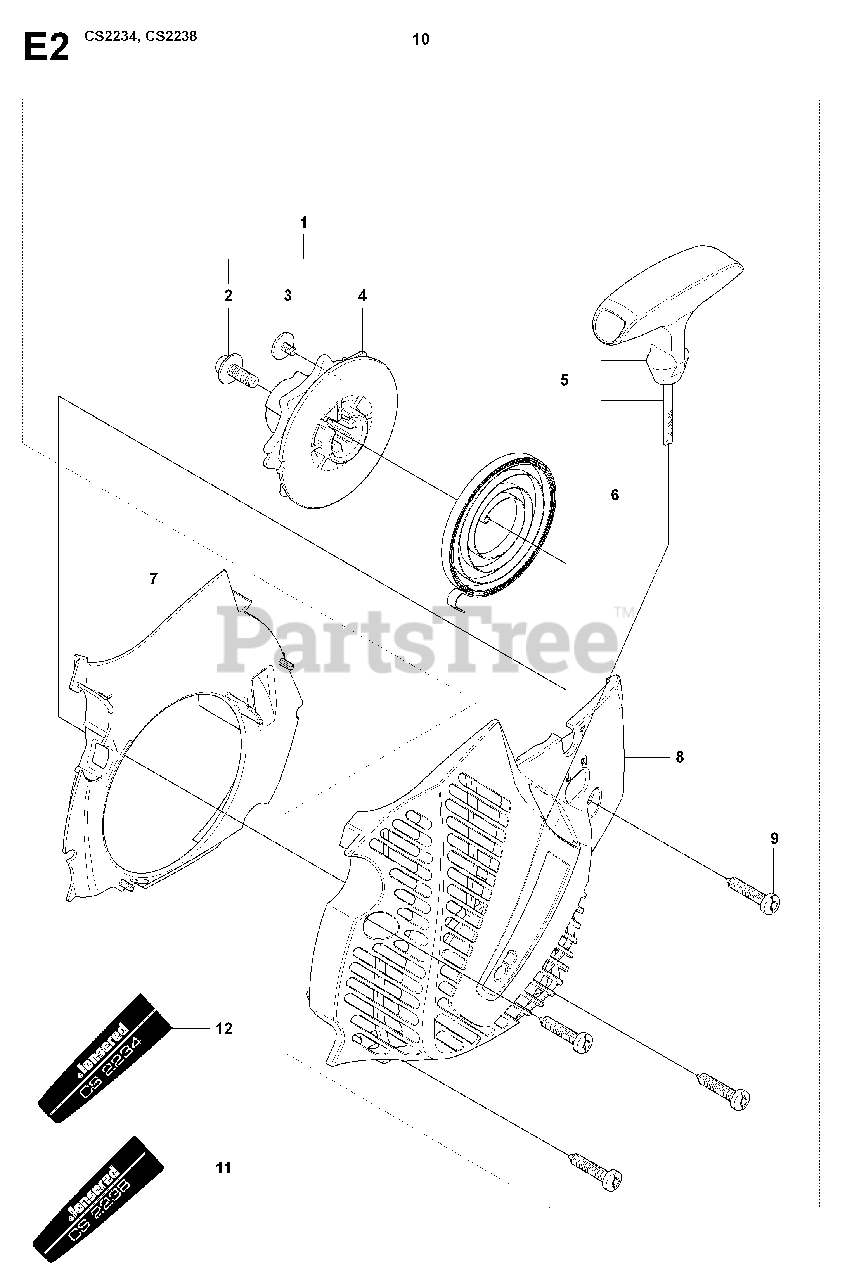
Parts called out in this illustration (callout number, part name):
1	KIT, STD STARTER
2	SCREW
3	SCREW
4	STARTER PULLEY
6	SPRING STARTER
9	SCREW M5.38-14X22.225MM
